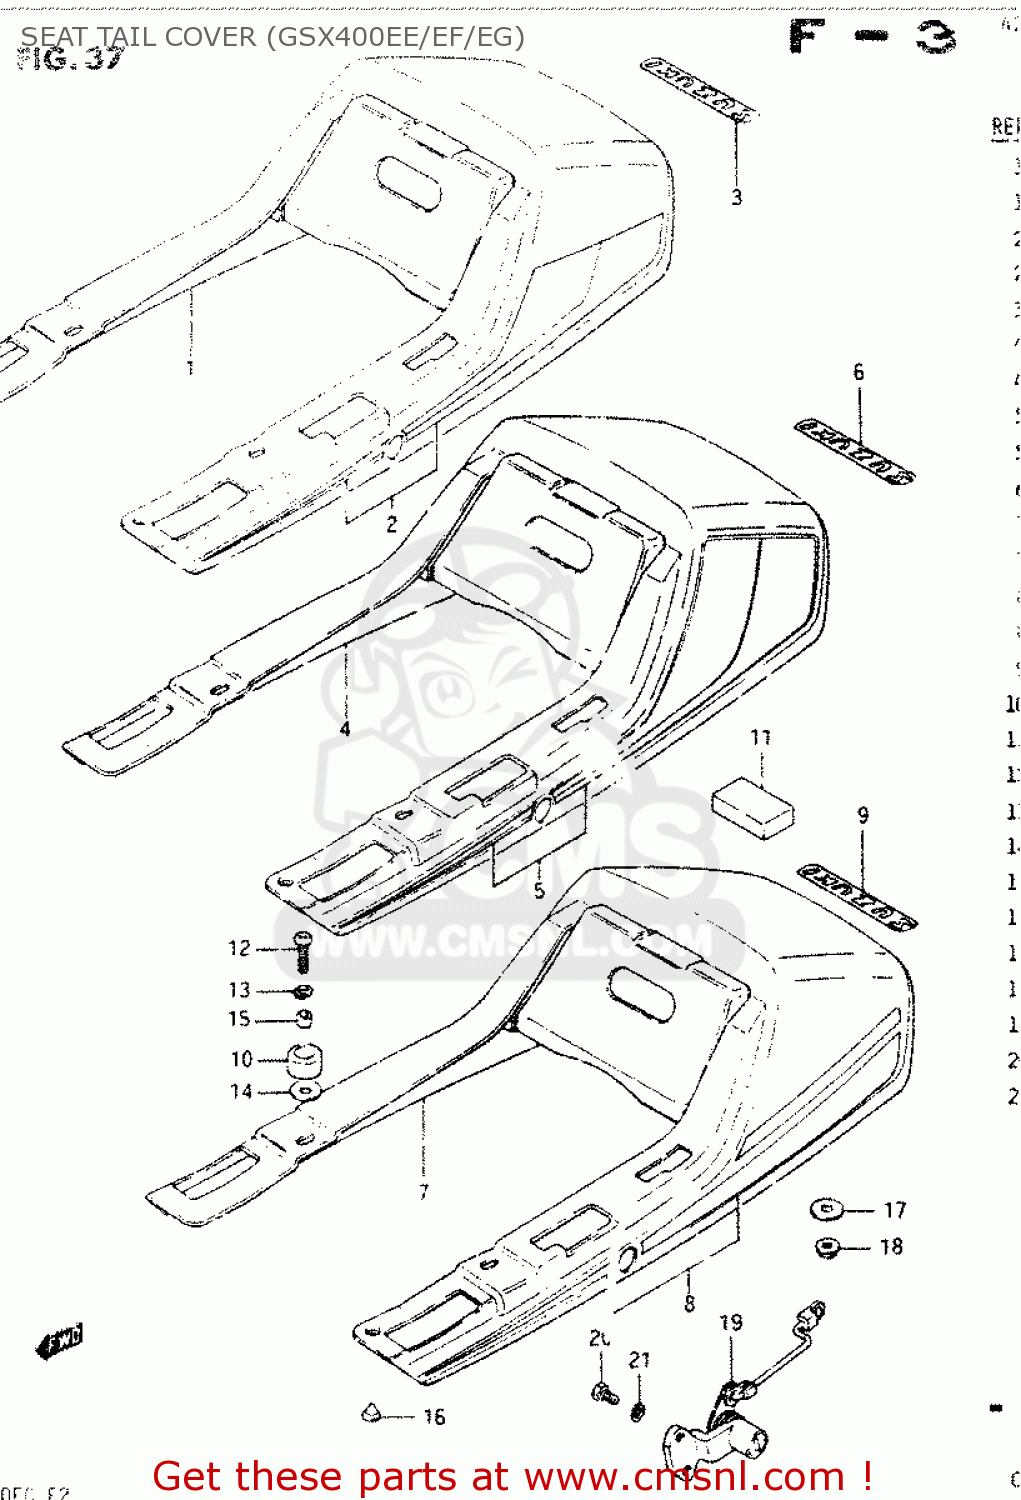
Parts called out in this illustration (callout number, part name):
1	COVER, SEAT TAIL (RED)
2	TAPE SET, SEAT TAIL COVER
3	EMBLEM(WHITE)
4	COVER, SEAT TAIL (RED)
5	TAPE SET, SEAT TAIL COVER
6	EMBLEM
7	COVER, SEAT TAIL (WHITE)
8	TAPE SET, SEAT TAIL COVER
9	EMBLEM
10	CUSHION,COVER
11	CUSHION
12	SCREW
13	WASHER,LOCK
14	WASHER (6.5X24X1.6)
15	SPACER
16	CUSHION
17	WASHER
18	NUT 6MM
19	LOCK ASSEMBLY,SEAT
20	BOLT
21	LOCK WASHER
